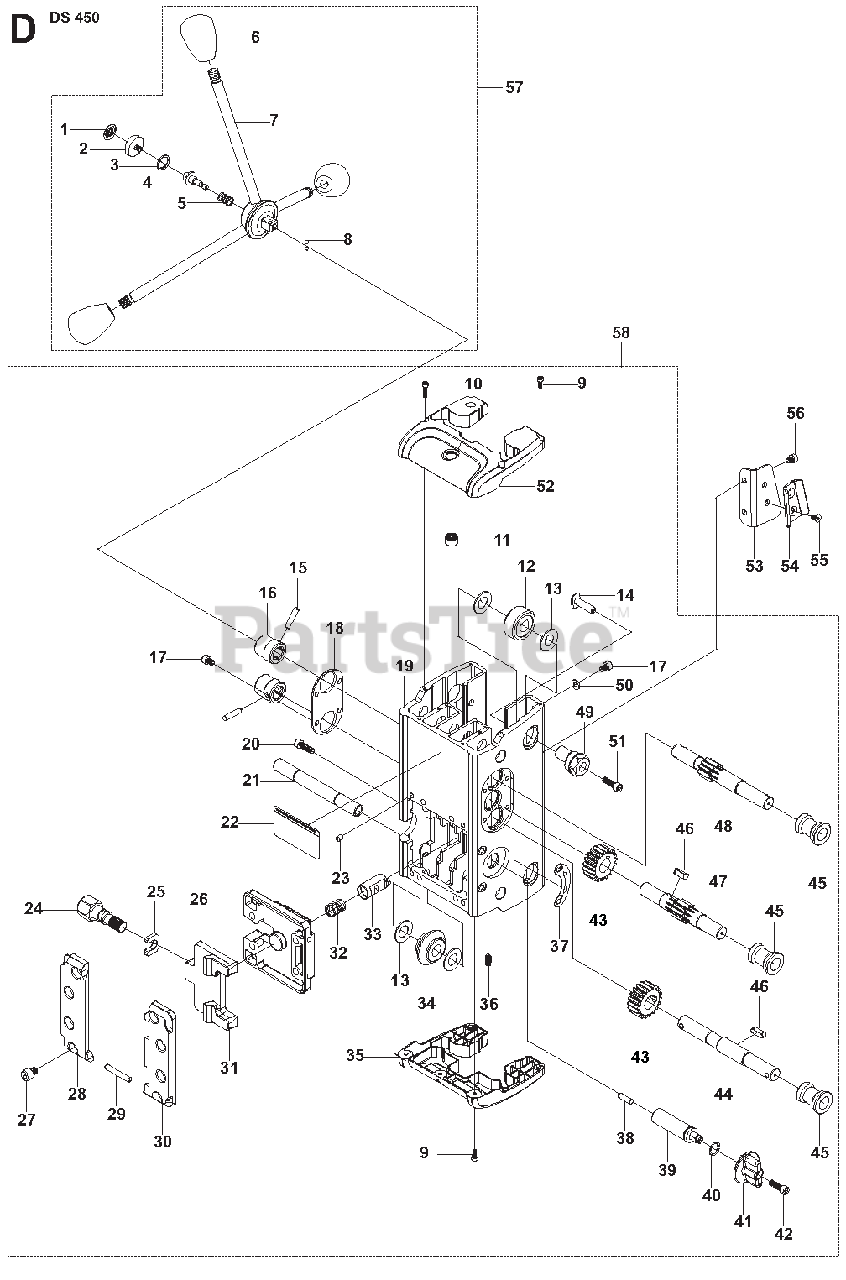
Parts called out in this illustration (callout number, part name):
15	PARALLEL PIN
20	SCREW IHSCM
23	PARALLEL PIN
51	SCREW IHSCM
